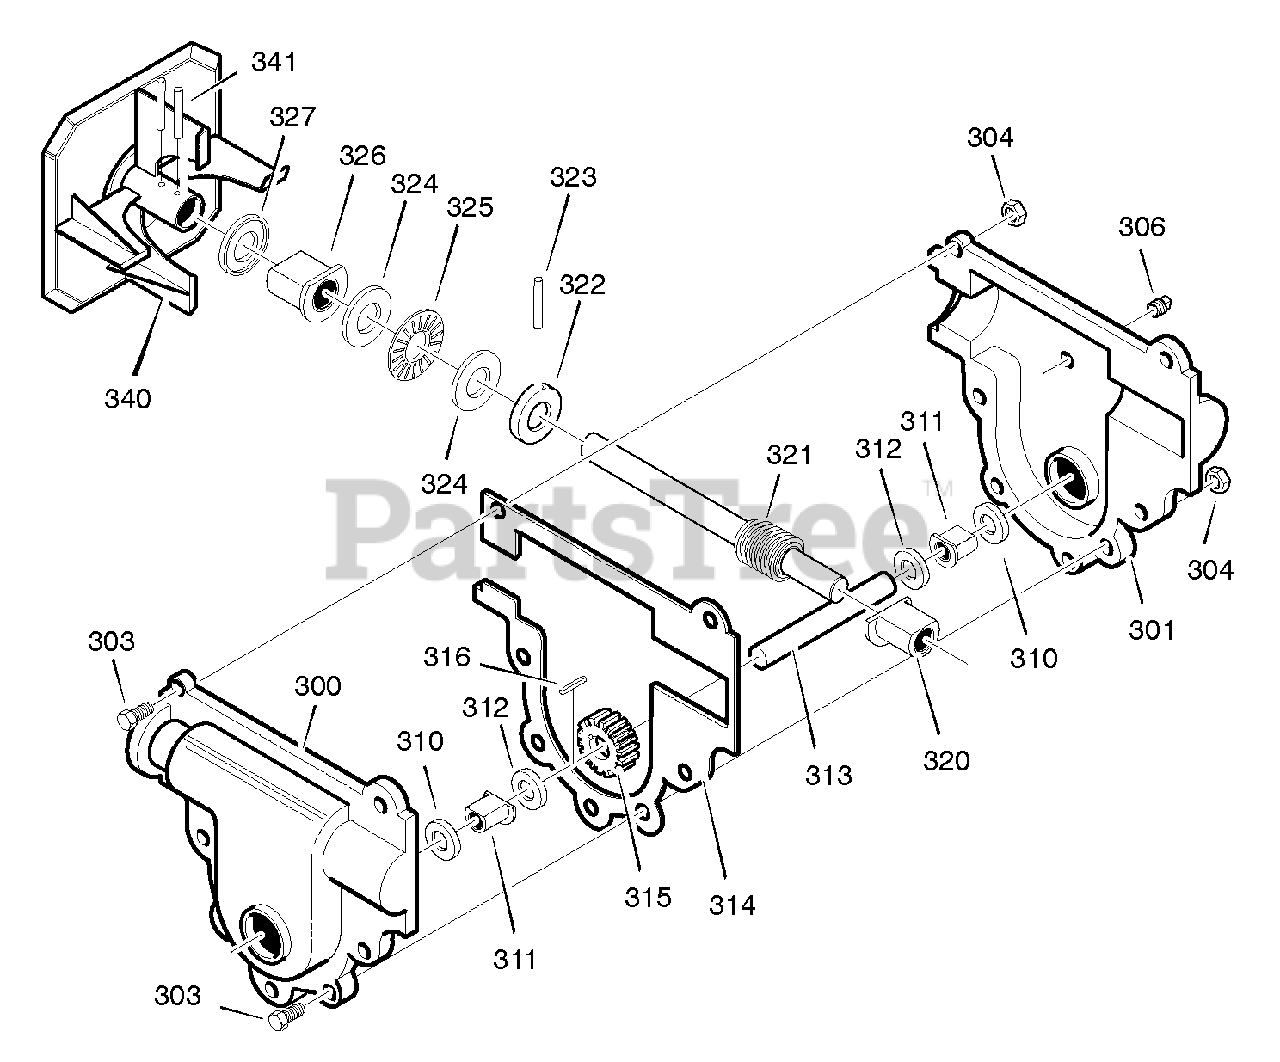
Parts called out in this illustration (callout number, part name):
300	CASE, GEAR, RH
301	CASE, GEAR, LH
306	SCREW
310	SEAL, OIL
311	BEARING, FL
312	WASHER, FLAT
313	SHAFT, OUTPUT
315	GEAR, WORM
316	KEY, WOODRUFF
320	BRNG, FL
321	SHAFT, INPUT
322	COLLAR, THRUST
323	PIN, SPRING
324	WASHER, FLAT
325	BRNG, ROLL
326	BRNG, FL
327	SEAL, OIL
341	PIN, SPRING
